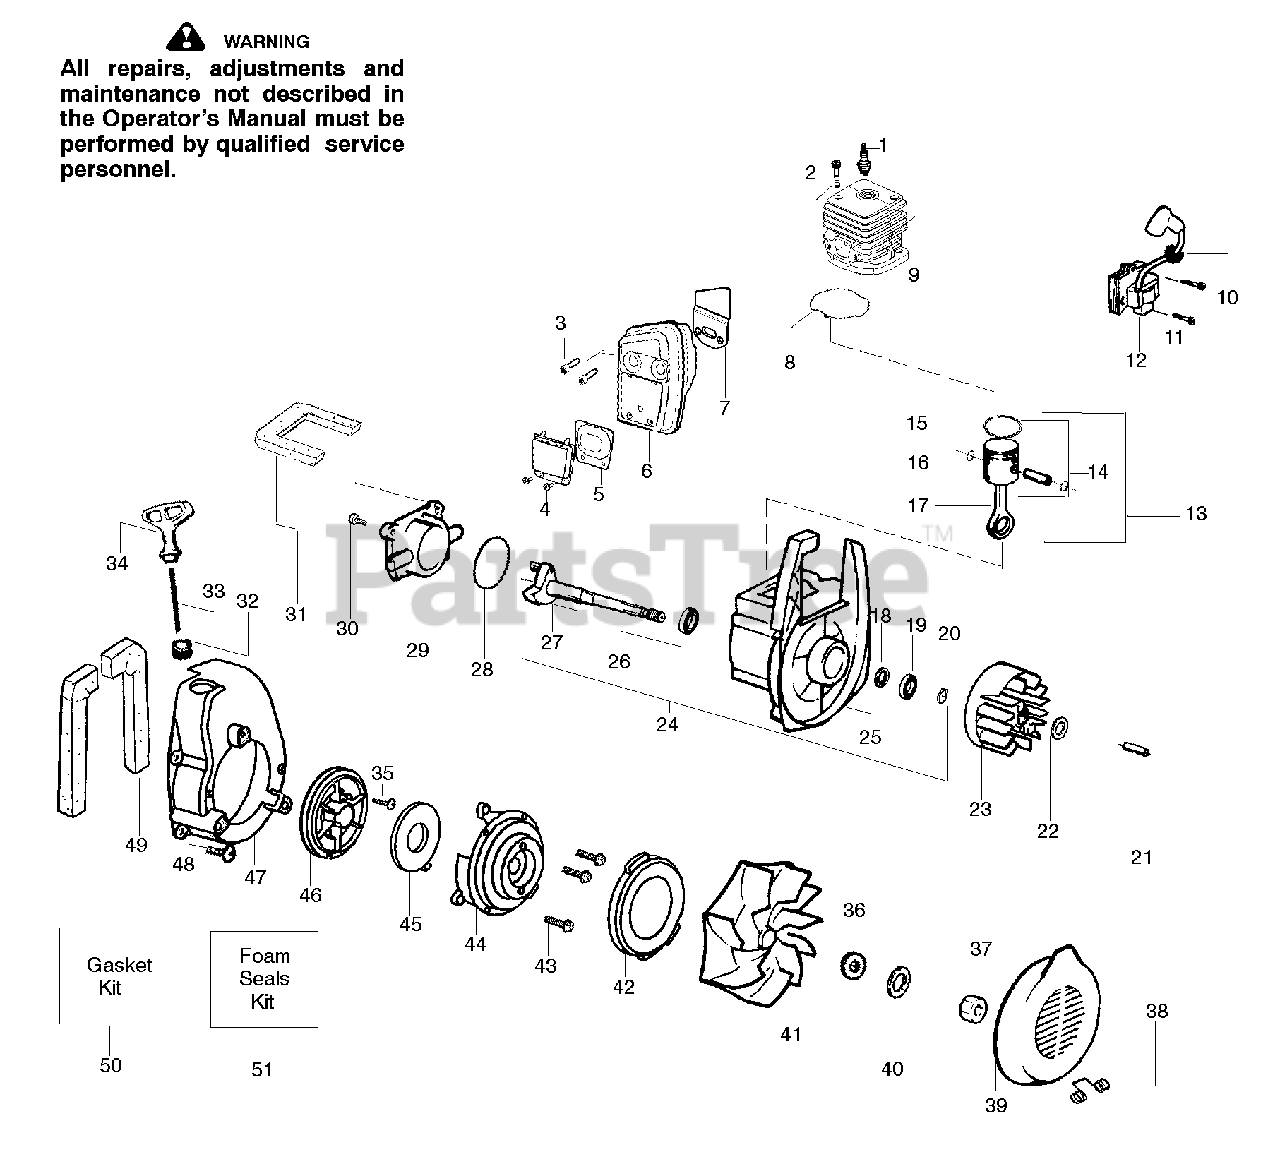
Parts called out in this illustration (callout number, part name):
1	Spark Plug (RCJ-6Y)
3	Screw-Muffler-Internal
5	Kit-Spark Screen
6	Kit-Muffler
7	Gasket-Baffle (kit)
8	Gasket-Cylinder (kit)
10	Grommet-Ign. Module
11	Screw-Ignition Module
12	Ignition Module
13	Kit-Piston/Rod
14	Kit-Piston
15	Piston Ring
16	Retainer-Piston Pin
17	Assy-Connecting Rod
18	Seal-Crankcase
19	Bearing-Outer
20	Retainer Ring-C’chaft
21	Spacer-Flywheel
23	Assy-Flywheel
24	Assy-Crankcase/Crank shaft
25	Assy-Crankcase
26	Bearing-Inner
27	Assy-Crankshaft
28	O-ring-C/case (kit)
29	Cover-Crankcase
30	Screw
31	Foam-219mm (kit)
32	Eyelet-Flange
33	Kit-Rope
34	Handle-Starter
36	Washer-Belleville
38	Spring-Return Cover
41	Kit-Impeller Assy.
44	Housing-Pulley
45	Spring-Starter
46	Kit-Starter Pulley
48	Screw
49	Foam-182mm (kit)
50	Kit-Gasket
51	Kit-Foam Seals
